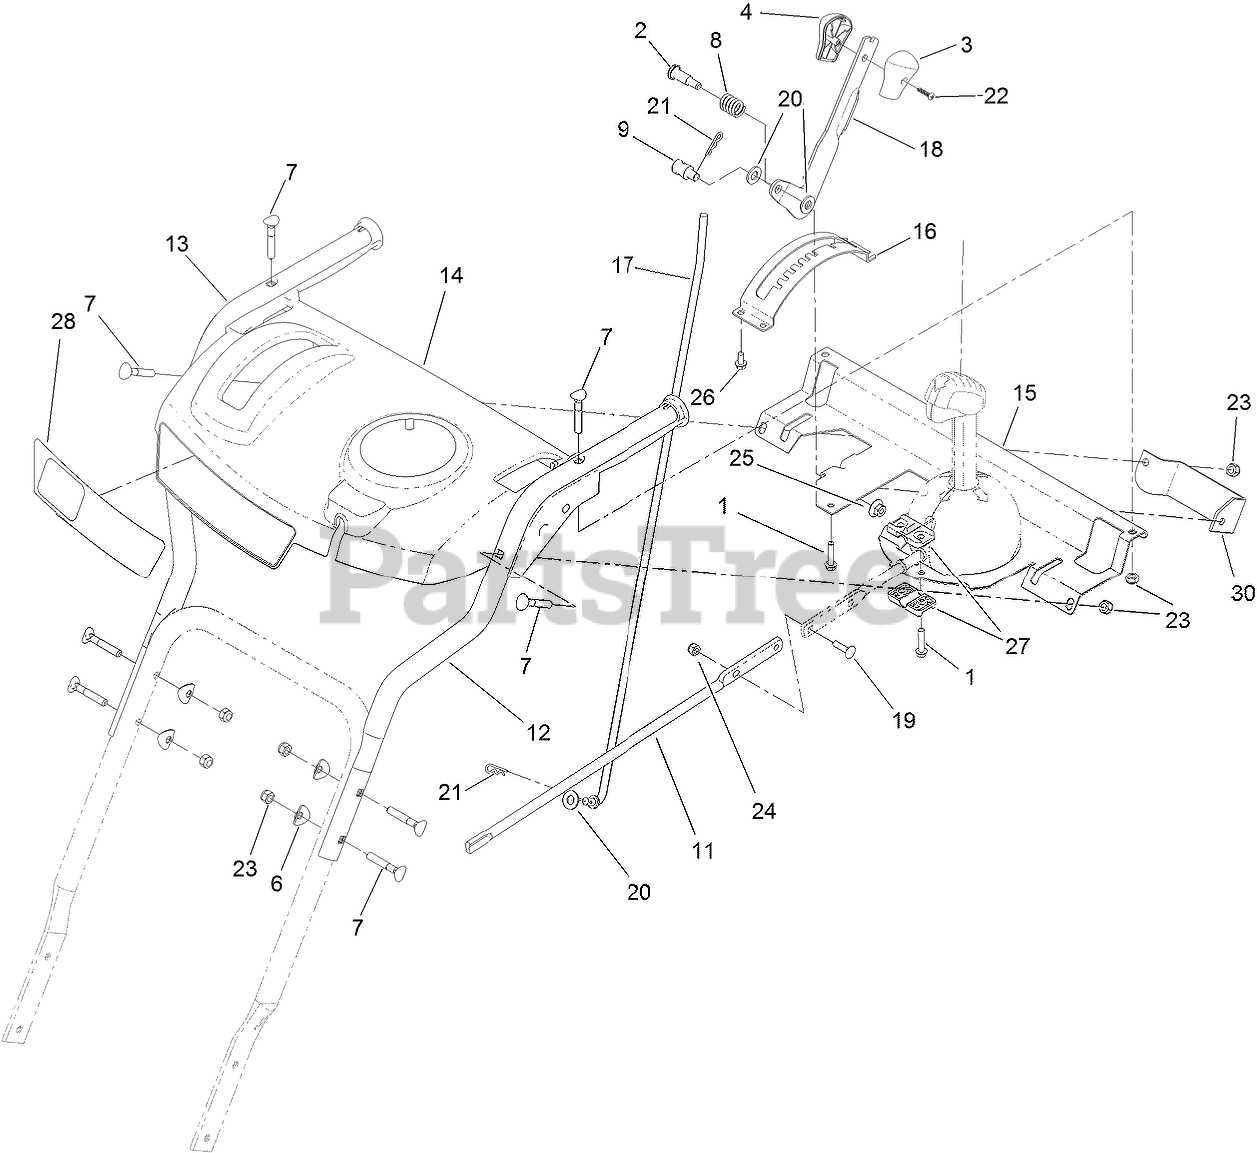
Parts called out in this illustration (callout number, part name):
1	SCREW-PLASTITE, HWH
2	SCREW-SHOULDER, HH
3	KNOB-SHIFT, LH
4	KNOB-SHIFT, RH
6	WASHER-CUP
7	SCREW-HANDLE
8	SPRING-COMPRESSION
9	TRUNNION-ROD
11	ROD-CHUTE, FRONT
12	HANDLE-UPPER, LH
13	HANDLE-UPPER, RH
14	PANEL-CONTROL, MASTER
15	SUPPORT-PANEL, CONTROL
16	MOUNT-SELECTOR, SPEED
17	ROD-SELECTOR, GEAR
18	SELECTOR-SPEED
19	BOLT-CARR
20	WASHER-FLAT
21	PIN-HAIR
22	SCREW-PPH
23	NUT-HEX
24	NUT-HEX
25	NUT-HEX FLG
26	SCREW-PLASTITE
27	SUPPORT-ROD
28	DECAL-PANEL, CONTROL
30	PLATE-SUPPORT, SHIFT
